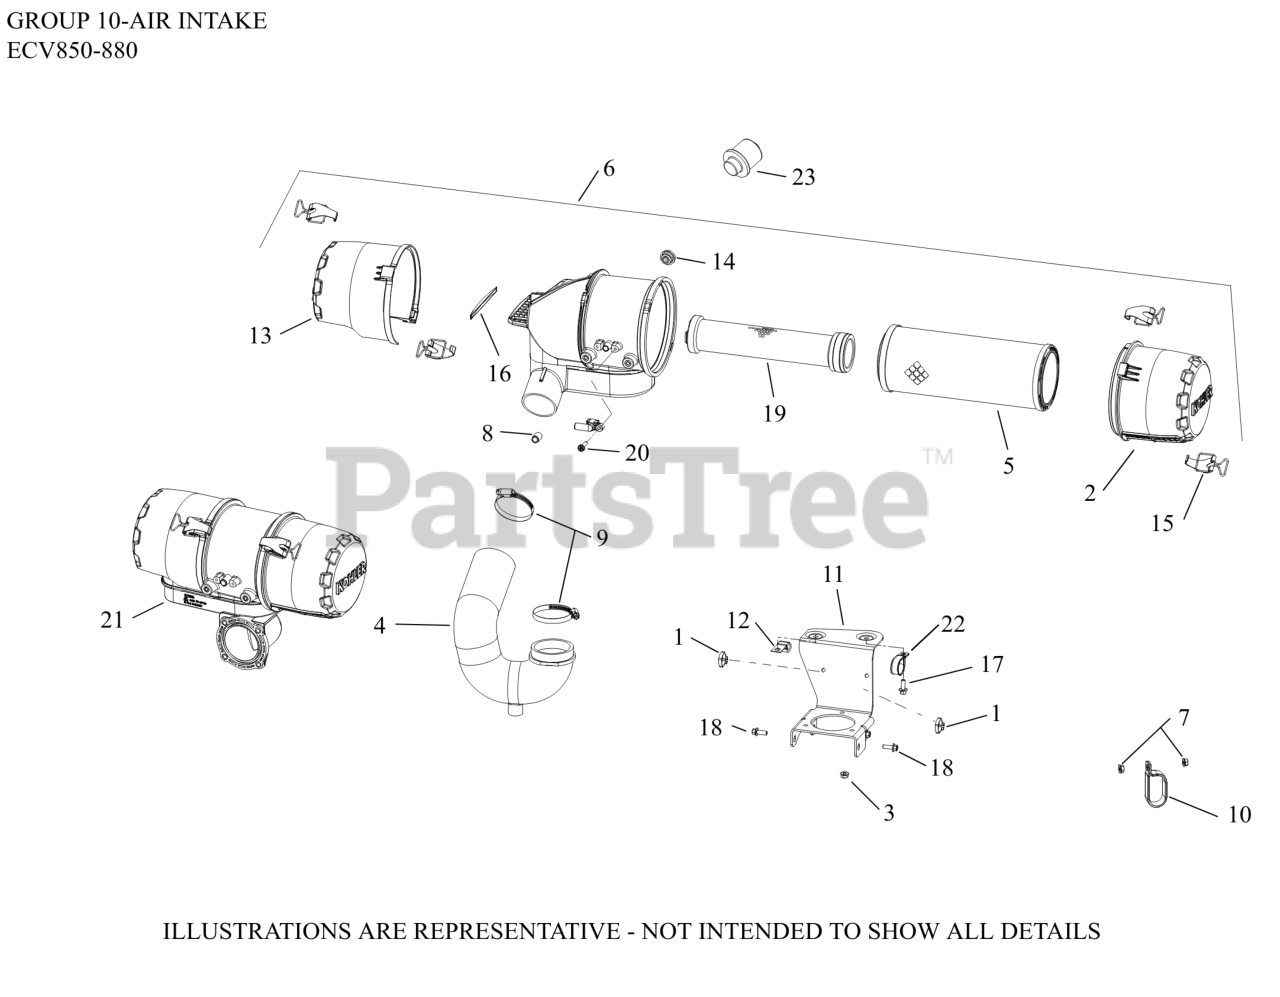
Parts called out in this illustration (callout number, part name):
1	CLIP, SNAP-IN-USE 25 018 05-S
2	COVER, AIR FILTER
3	NUT, FLG M6X1.0
4	HOSE, AIR CLEANER
5	ELEMENT, AIR FILTER - PRIMARY
6	FILTER ASSEMBLY, AIR
7	NUT, HEX FLANGE
8	CAP, MASKING
9	NUT, HEX FLANGE
9	CLAMP, HOSE
10	CLAMP, INSULATED DOUBLE
11	BRACKET, HDAC SUPPORT
12	CLIP, CABLE (KM)
13	COVER, RAIN CAP
14	PLUG, HOLE
15	CLIP ASSEMBLY
16	DAMPER, FOAM INSERT
17	SCREW, FLG M6X1.0X16
18	SCREW, FLG M6X1.0X16
19	ELEMENT, AIR FILTER - SAFETY
NI	RETAINER, WIRE HARNESS
